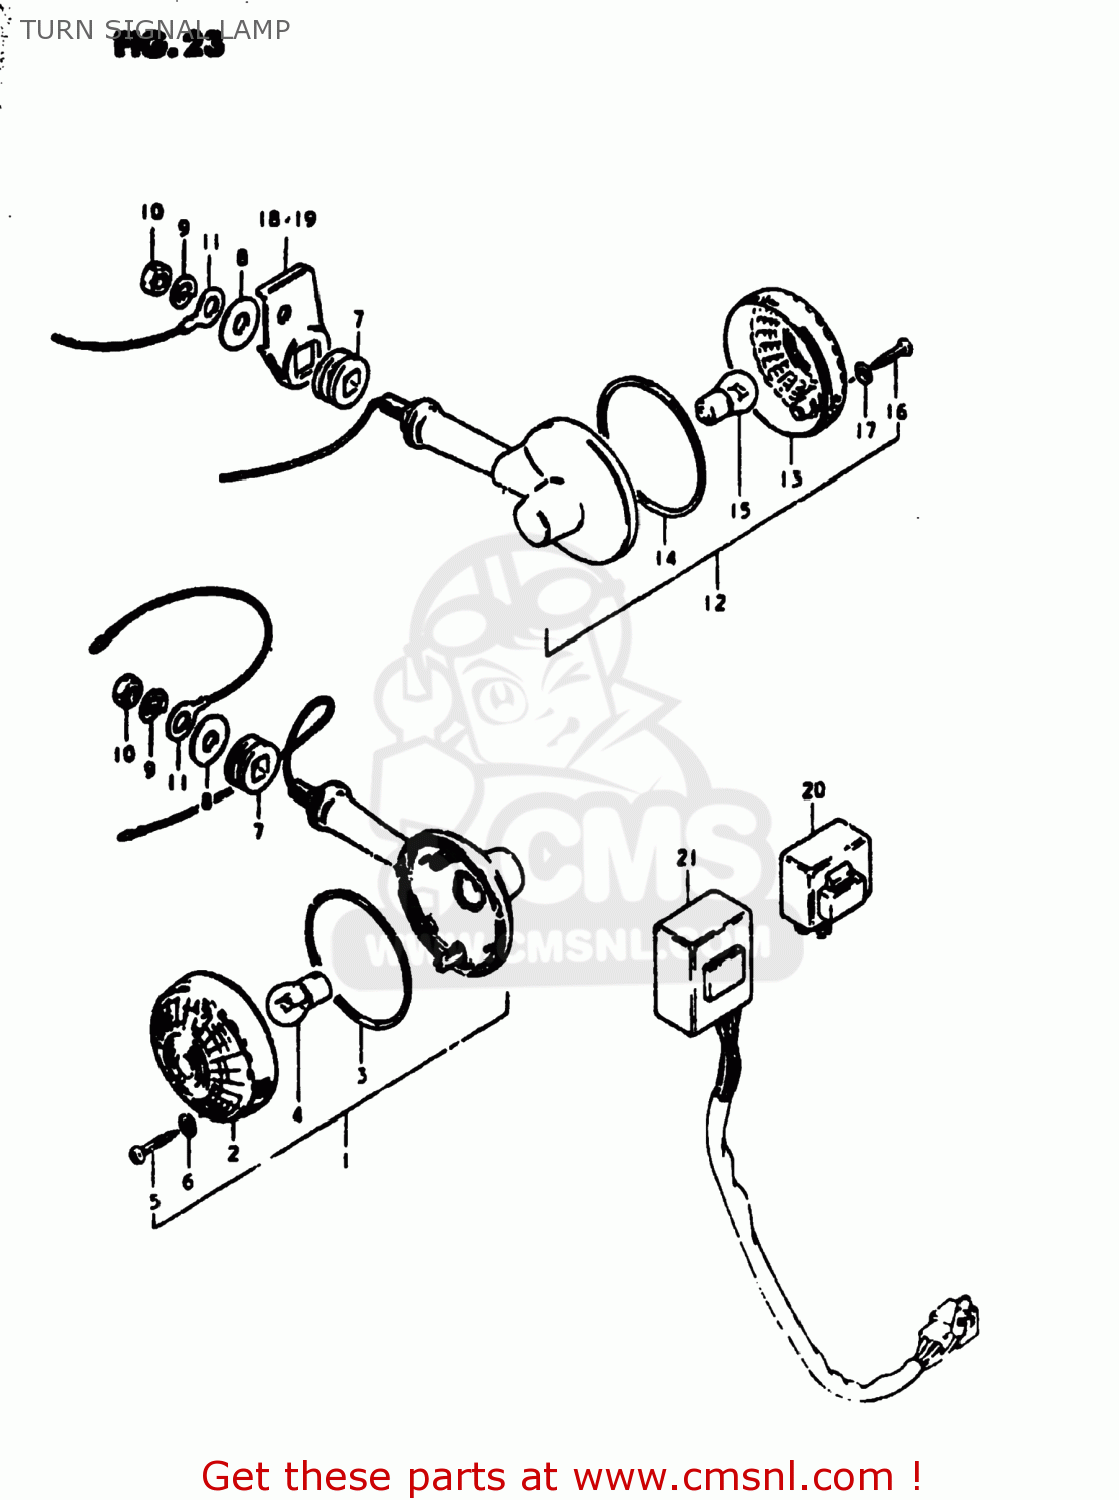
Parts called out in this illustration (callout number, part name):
1	LAMP ASSEMBLY,FRONT TURN SIGNAL
2	LENS
3	GASKET (NAS)
4	BULB(12V23W,STANLEY,A4577A)
5	BOLT
6	GASKET (NAS)
7	CUSHION
8	WASHER
9	LOCK WASHER
10	NUT
11	LEAD WIRE,EARTH
12	LAMP ASSEMBLY,FRONT TURN SIGNAL
13	LENS
14	GASKET (NAS)
15	BULB(12V23W,STANLEY,A4577A)
16	BOLT
17	GASKET (NAS)
18	BRACKET,RR TURNSIGNAL LAMP,R
19	BRACKET,RR TURNSIGNAL LAMP,L
20	RELAY,TURN SIGNAL
21	UNIT,TURN SIGNAL CONTROL
